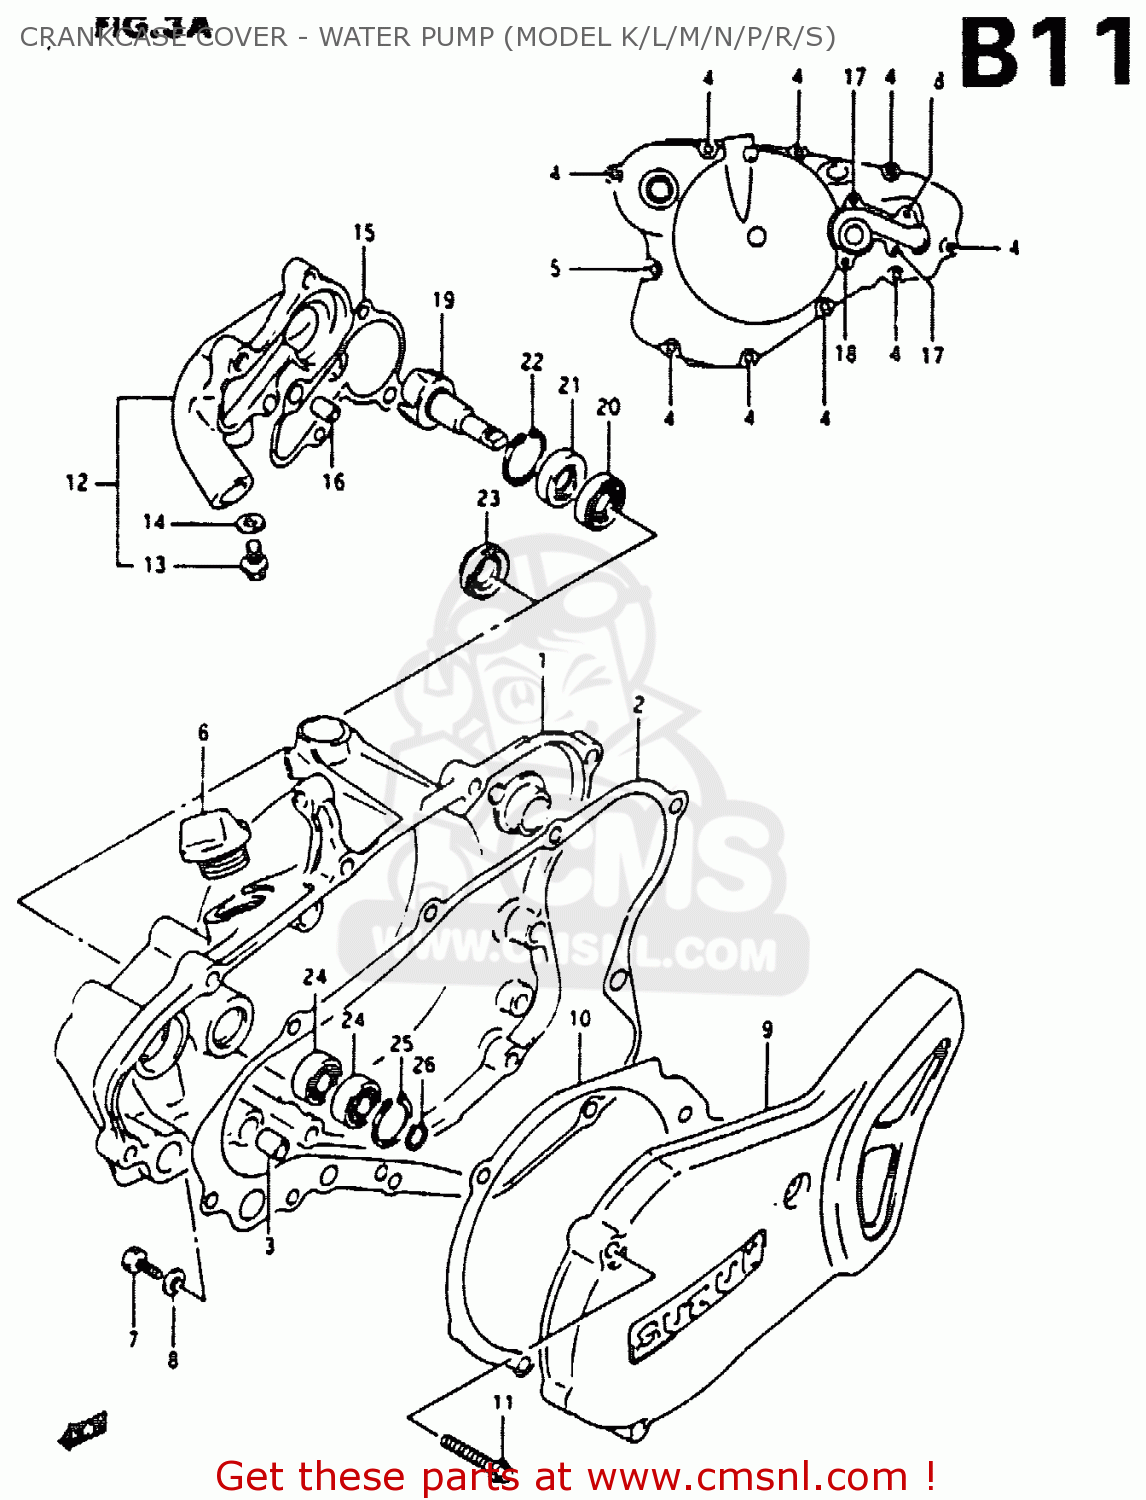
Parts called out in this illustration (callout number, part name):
1	COVER,CLUTCH
2	GASKET,CLUTCH COVER (NAS)
3	PIN
4	BOLT
5	BOLT
6	PLUG SET
7	SCREW(6X10)
8	GASKET(6.2X11X1).2 (NAS)
9	COVER,MAGNETO
10	GASKET,MAGNETO COVER (NAS)
11	BOLT
12	CASE,WATER PUMP
13	BOLT, DRAIN
14	WASHER
15	GASKET,WATER PUMP CASE (NAS)
16	PIN
17	BOLT
18	BOLT
19	IMPELLER,WATER PUMP
20	SEAL,OIL(12X24X3.6)
21	SEAL,OIL(12X24X6.4)
22	CIRCLIP
23	SEAL,WATER PUMP OIL
24	BEARING
25	CIRCLIP
26	CIRCLIP
